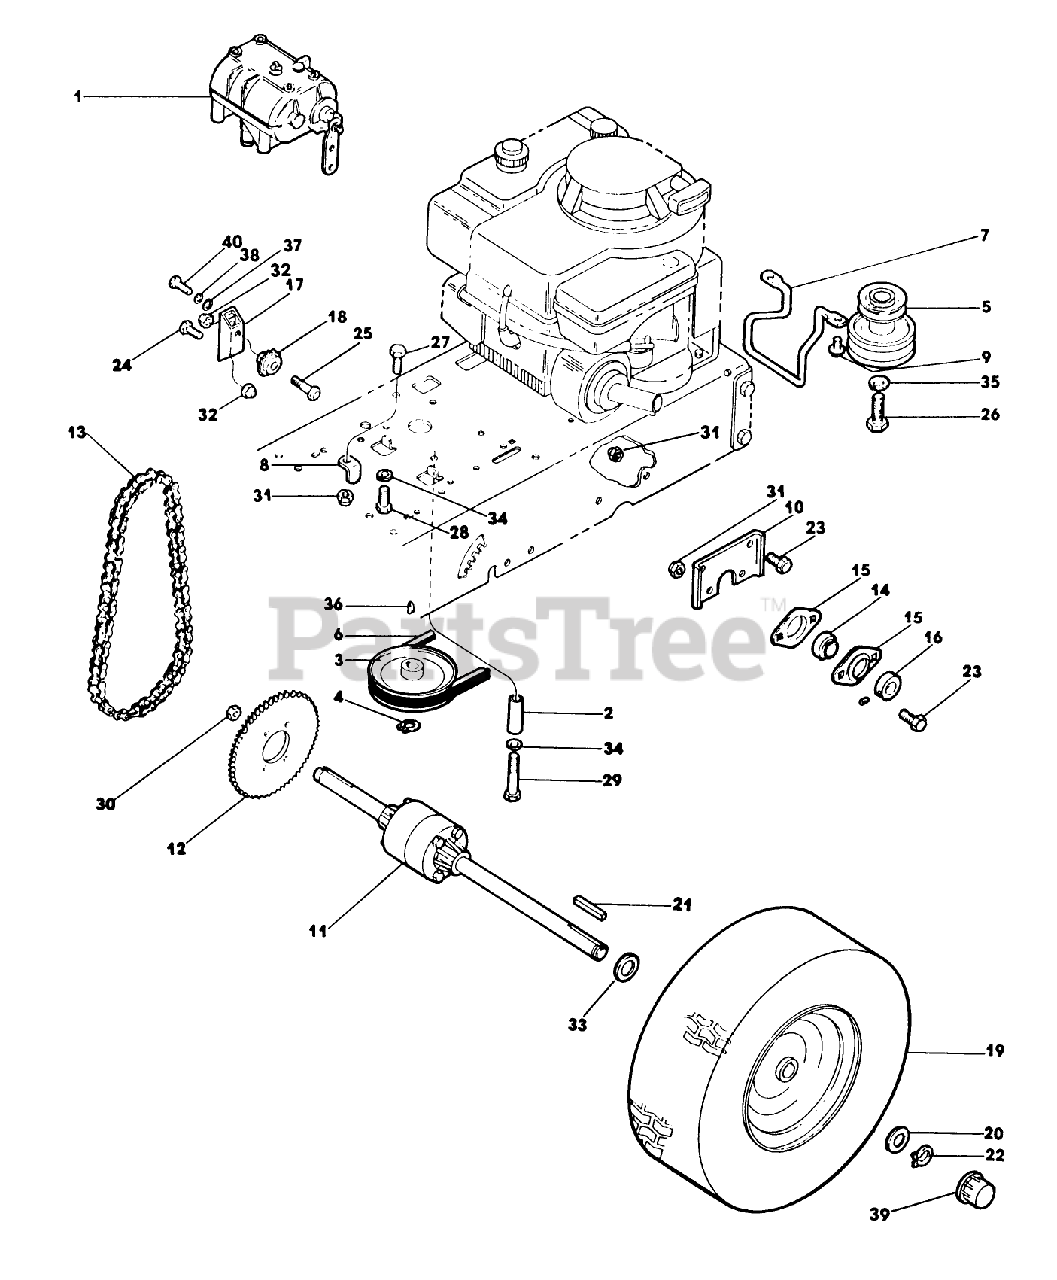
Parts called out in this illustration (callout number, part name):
2	GUIDE - BELT
6	V-BELT S
9	SCREW-THREAD FRMG
14	DISCONTINIUED
15	FLANGETTE-BEARING
16	COLLAR-BEARING
17	IDLER SPRKT BRKT WA*B
20	WASHER
22	RING-RETAINING
23	SCREW - HEX
27	SCREW
31	NUT
32	NUT-LOCKING
38	WASHER
